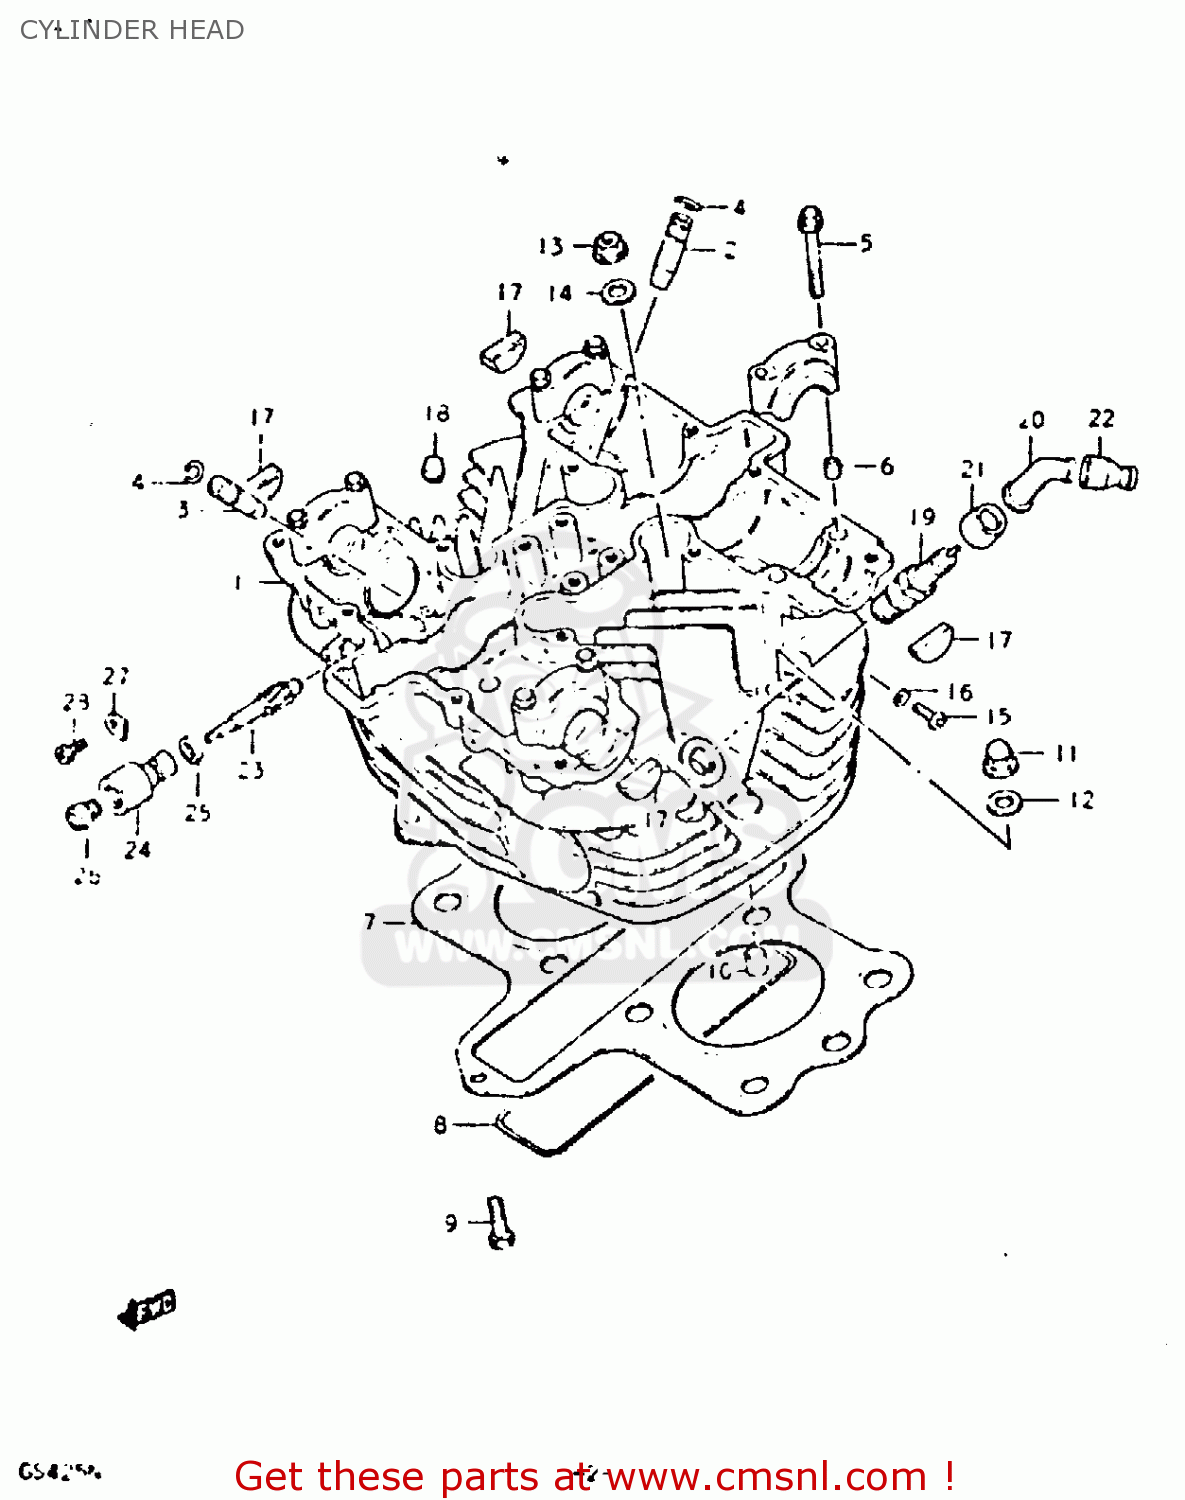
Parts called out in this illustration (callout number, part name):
1	HEAD SET,CYLINDER
2	GUIDE,VALVE
3	GUIDE,VALVE
4	RING,SNAP
5	BOLT(6X39)
6	PIN(6.2X8X11)
7	GASKET,CYLINDER HEAD (MCA)
8	O RING(D:3,ID:26X157)
9	BOLT
10	PIN
11	NUT
12	GASKET(10.5X22X2) (NAS)
13	NUT
14	WASHER(10.5X22X2.3)
15	SCREW 5X20
16	GASKET(5.3X9.3X1.2) (NAS)
17	PLUG
18	PAD
19	PLUG,SPARK
20	CAP,SPARK PLUG
21	SEAL,SPARK PLUG
22	SEAL,SPARK PLU
23	GEAR,TACHOMETER DRIVEN
24	SLEEVE,TACHOMETER DRIVE
25	SEAL,TACHOMETER DRIVEN
26	SEAL
27	PLATE,TACH DRIVE GEAR SLEEVE
28	SCREW(5X12)
